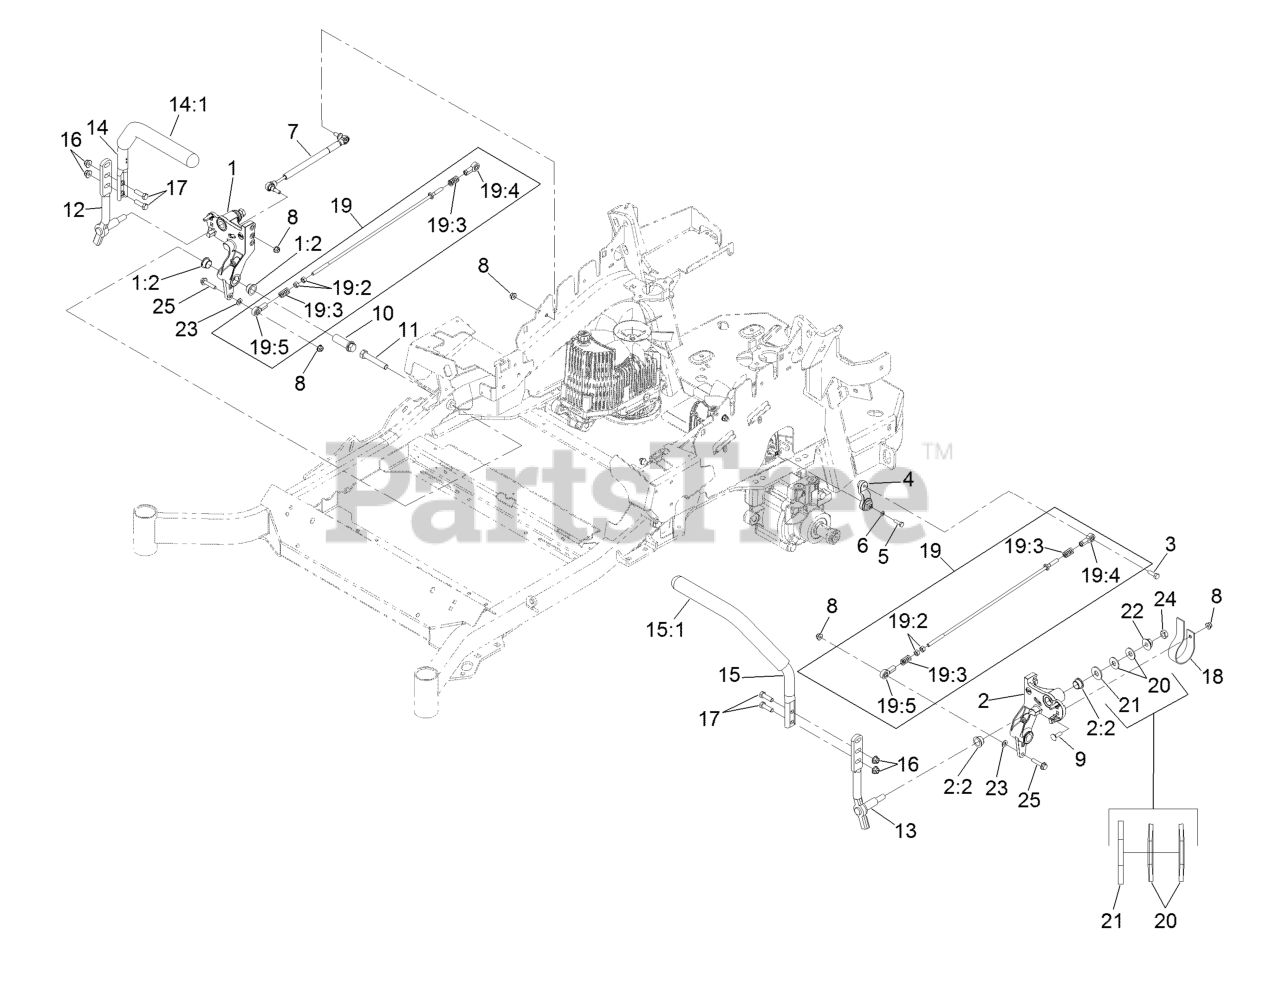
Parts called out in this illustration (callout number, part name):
1	RH MOTION CONTROL AND BUSHING ASM
1:2	BUSHING-FLANGE
2	LH MOTION CONTROL AND BUSHING ASM
2:2	BUSHING-FLANGE
3	SCREW-HH, THREAD LOCKING
4	ARM-CONTROL, PUMP
5	SCREW-HH
6	WASHER-SPRING
7	DAMPER-CONTROL, MOTION
8	NUT-HF, NI
9	BOLT-CARR
10	HUB-THREADED
11	SCREW-HH
12	LEVER-CONTROL MOTION, RH
13	LEVER-CONTROL MOTION, LH
14	RH STEERING HANDLE ASM
14:1	GRIP-LEVER, CONTROL
15	LH STEERING HANDLE ASM
15:1	GRIP-LEVER, CONTROL
16	NUT-HF, NI
17	SCREW-HH
18	SPRING-LEAF
19	PUMP LINKAGE REAR ASM
19:2	NUT-HEX
19:3	SPRING-COMPRESSION
19:4	BALLJOINT-LH
19:5	BALLJOINT-RH
20	WASHER-SPRING
21	WASHER-FLAT
23	WASHER-PLAIN
24	NUT-JAM
25	SCREW-HHF
